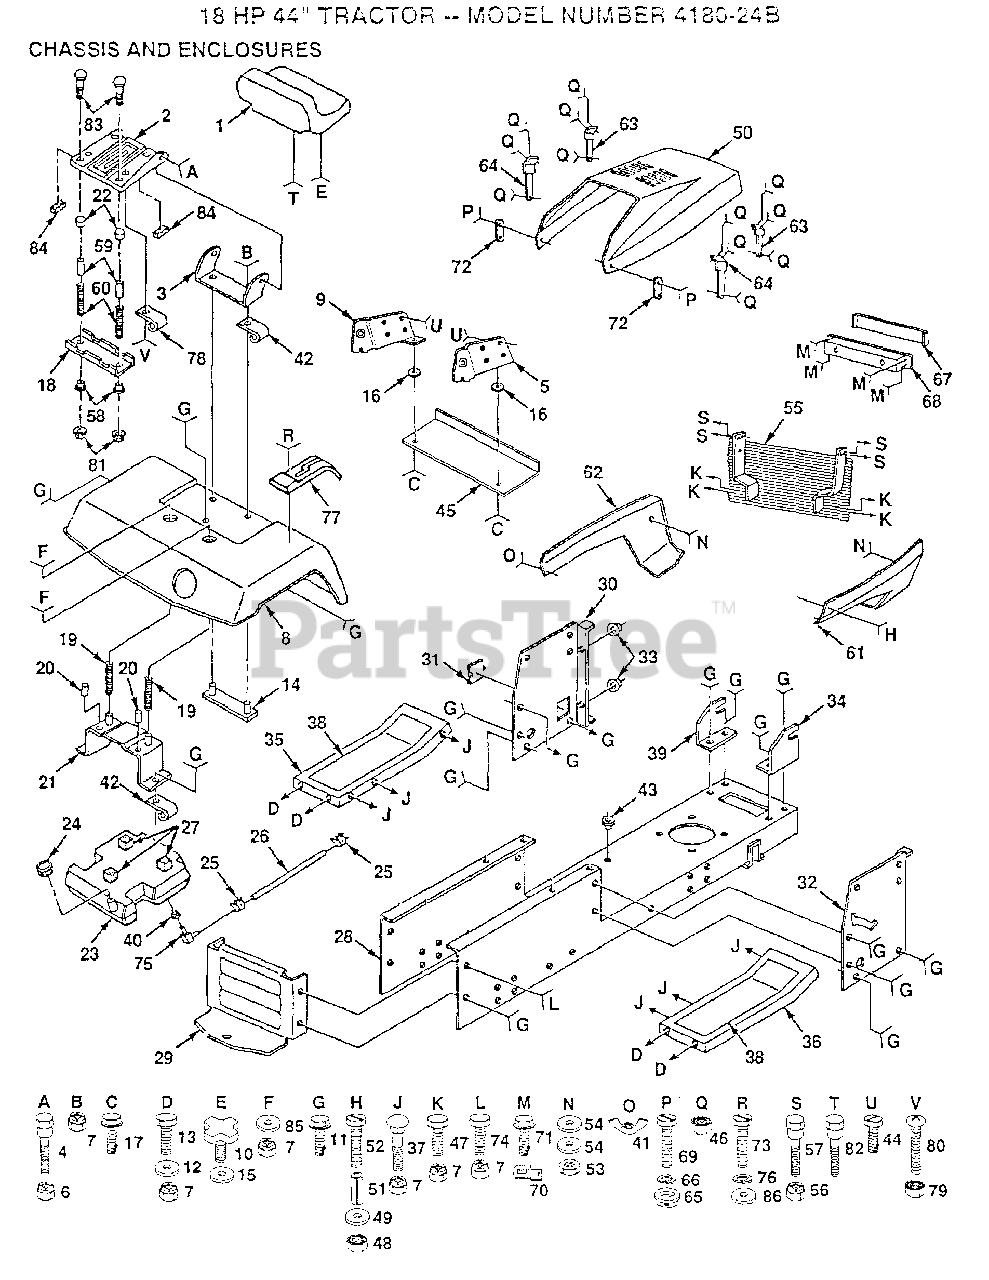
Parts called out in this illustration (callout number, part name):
5	SUPPORT RH YTH
8	FENDER
9	SUPPORT LH YTH
10	"KNOB 1/2"" YT"
11	SCREW
12	WASHER
15	WASHER
16	WASHER
17	SCREW
18	BRKT SWITCH
19	SPRING COMPRESSIO
20	NUT-PUSH YT
22	CAP SPRING
25	HOSE CLAMP
26	FUEL LINE T
27	PAD-SPACER LT
28	CHASSIS
29	DRAW BAR
30	PANEL DASH LH
31	COVER ACCESS
32	DASH PANEL RH
33	SNAP BUSHING T
34	SUPPORT RH YTH
37	BOLT
38	FOOTREST PAD
39	SUPPORT LH YTH
40	BUSHING OUTLET T
42	CLIP T
44	SCREW
46	NUT
47	BOLT
49	WASHER
51	SPACER LT
52	SCREW
54	WASHER PM
58	BUSHING
59	SPACER SPLIT
60	SPRING COMPRESSED
62	SIDE PANEL LH
65	WELDNUT
66	LOCKWASHER
67	LENS LT
69	SCREW
70	"""J"" FASTENER LT"
72	HOOD LATCH T
73	SCREW
75	FUEL TANK STEM GT
76	"WASHER,LOCK"
77	CONSOLE SHIFTER
79	"NUT,KEPS"
82	"BOLT,SHOULDER"
84	STRIP FORM
85	WASHER
86	WASHER
